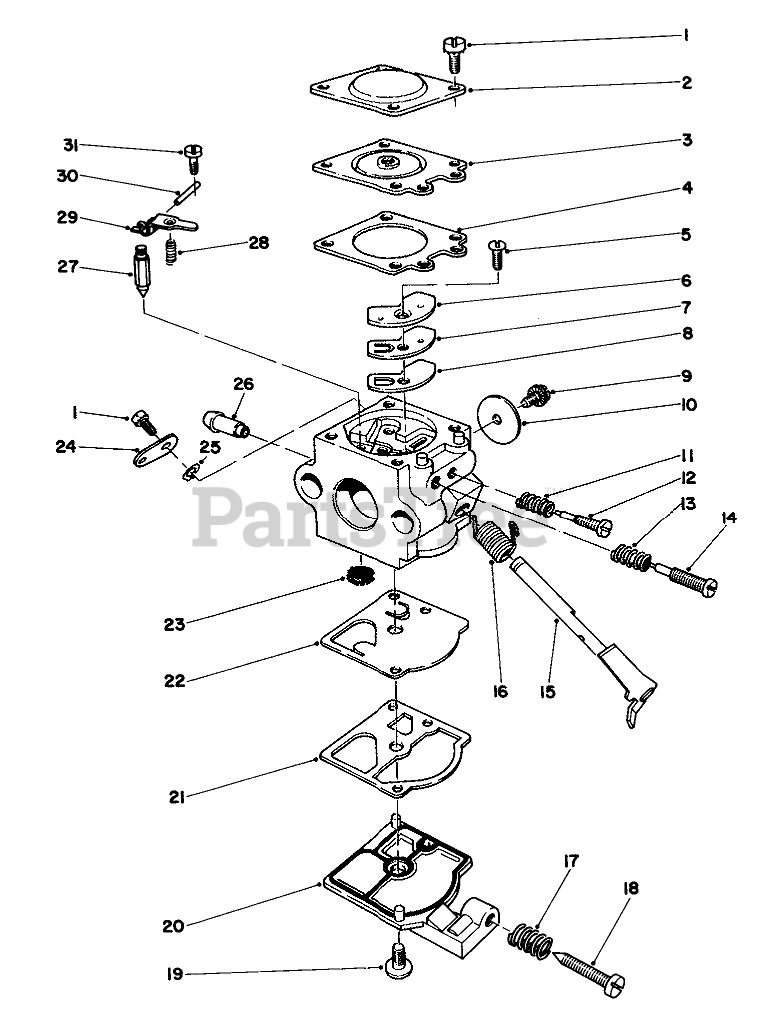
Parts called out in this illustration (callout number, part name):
1	Screw
2	Cover, Diaphragm
3	METERING DIAPHRAGM
4	Gasket, Diaphragm
5	Screw-Circuit Plate
6	Plate, Circuit
7	Diaphragm Circuit Plate
8	Gasket-Circuit Plate
9	Screw-Throttle Valve
10	Valve-Throttle
11	Spring, Needle
12	Needle-Idle
13	Spring, HS Needle
14	Needle, HS
15	Shaft Assembly-Throttle
16	Spring-Throttle Lever
17	Spring-Idle Screw
18	Screw-Idle Adjust
19	Screw
20	Cover-Fuel Pump
21	PUMP GASKET
22	Diaphragm Fuel Pump
23	Inlet Screen
24	Lever-Throttle
25	Ring-Throttle Retainer
26	Fitting Fuel Inlet
27	INLET NEEDLE VALVE
28	METERING LEVER SPRING
29	Lever Metering
30	Metering Lever Pin
31	Screw-Metering Pin
